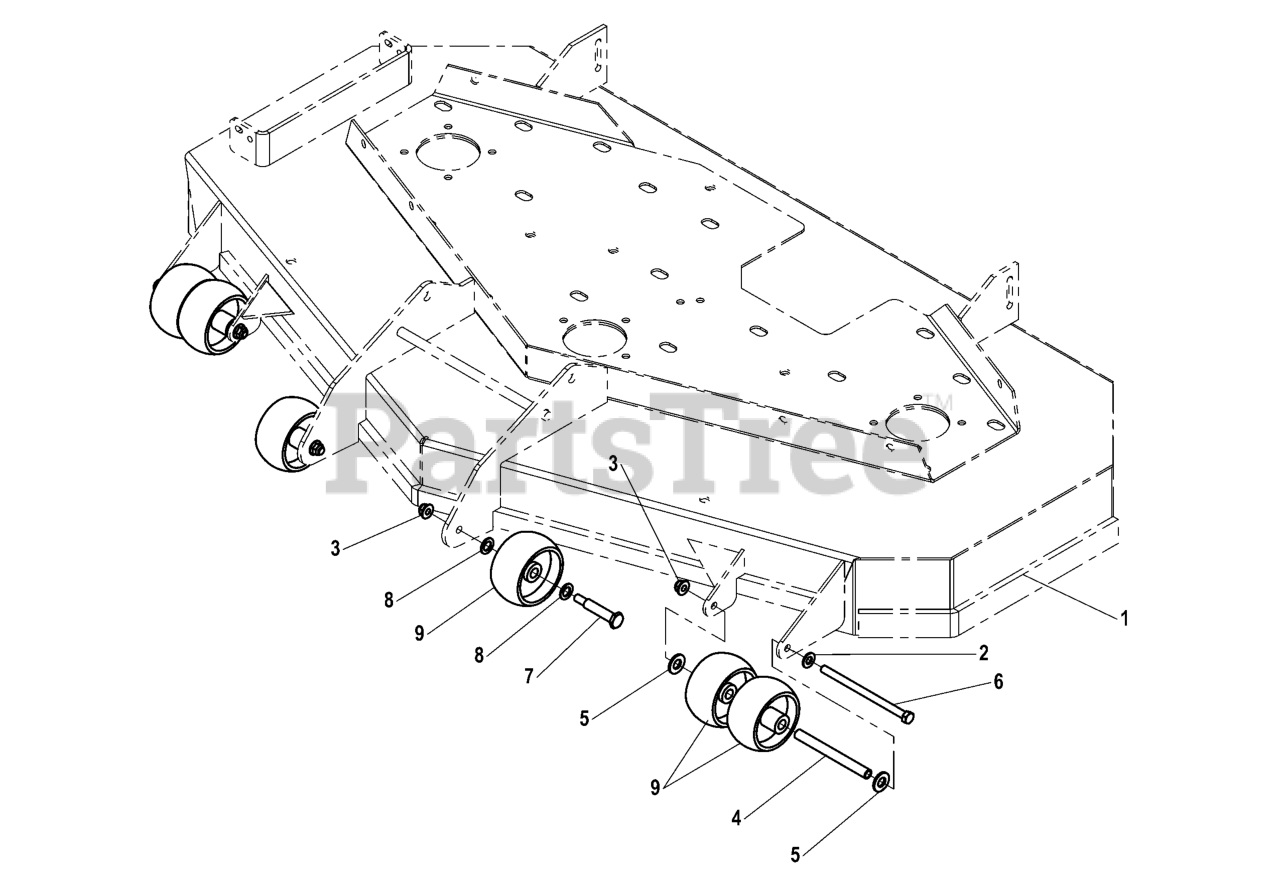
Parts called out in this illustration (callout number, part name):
1	MOWER DECK
2	WASHER, 3/8 SAE
3	NUT, 3/8-16 Hex Nylock Flange
4	SPACER, .38 X .50 X 5.06
5	WASHER, 1/2 SAE
6	BOLT, 3/8-16 X 6" GD5 CZ
7	BOLT, REAR WHEEL
8	WASHER,.516IDX.875ODX.06,FLAT,ZC/CL
9	WHEEL- 2.00 WIDE 3.88 DIA 0.531ID POLY
